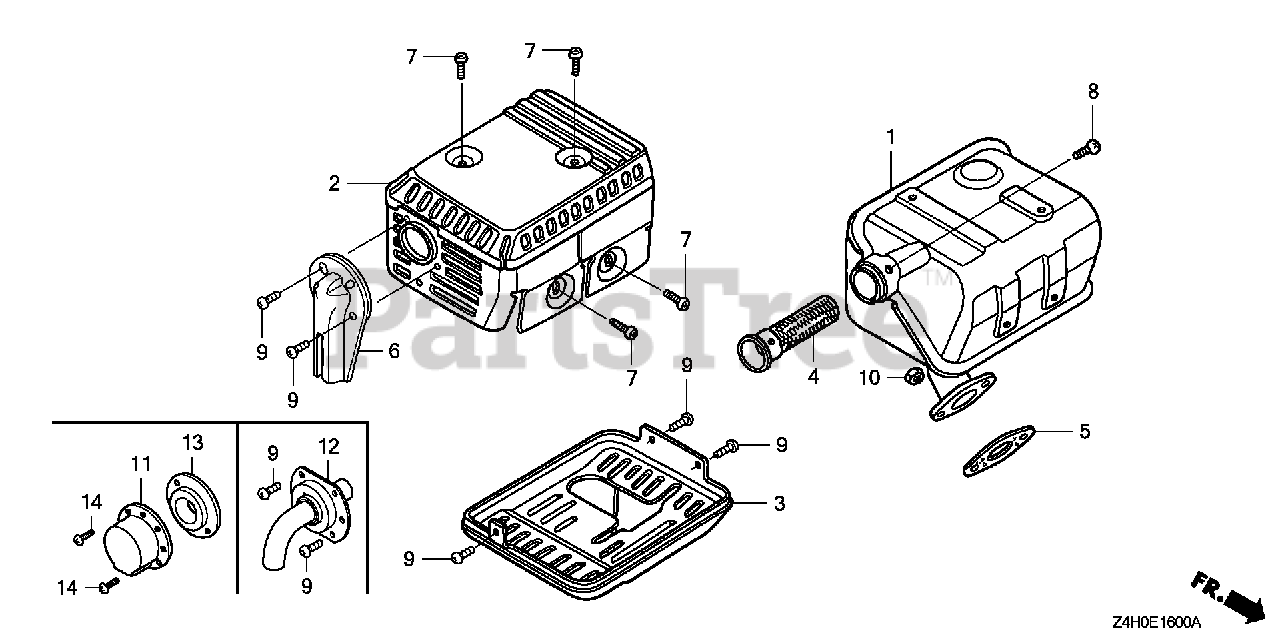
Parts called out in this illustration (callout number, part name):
1	MUFFLER (STD)
1	MUFFLER (ARRESTER)
2	PROTECTOR, MUFFLER (STD) (BLACK)
4	ARRESTER, SPARK
5	GASKET, MUFFLER
6	DEFLECTOR, MUFFLER
7	SCREW, TAPPING (5X8)
8	SCREW, TAPPING (4X6)
9	SCREW, TAPPING (4X6)
10	NUT, HEX. (8MM)
